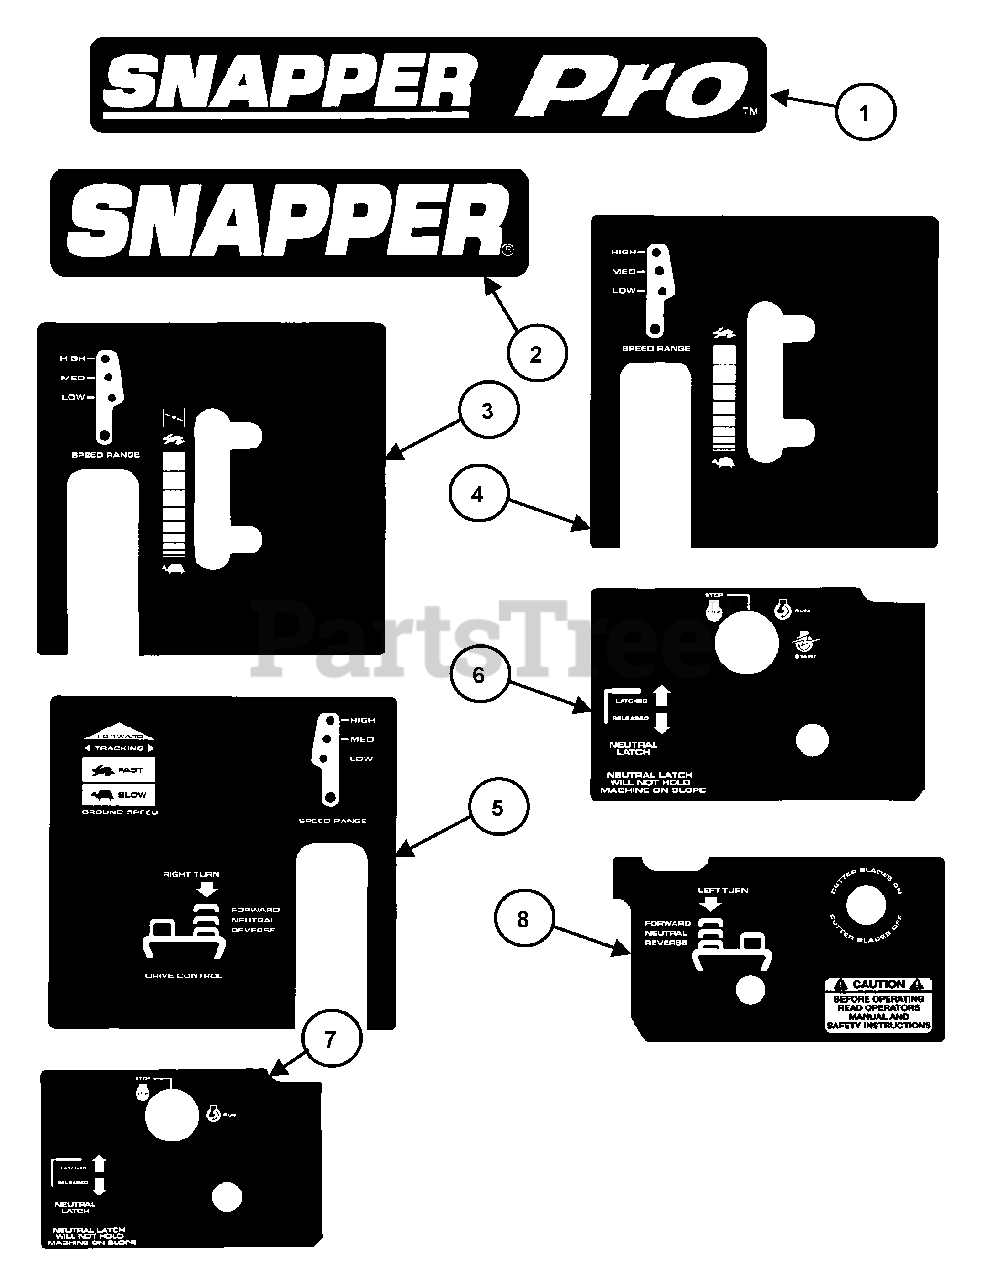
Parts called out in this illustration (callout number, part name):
1	DECAL, Snapper Pro
2	8" MOLDED LOGO, SNAPPER
3	DECAL, Left Panel, Throttle
4	DECAL, Left Panel, Throttle w/o Choke
5	DECAL, Right Panel, Instruction
6	DECAL, Right Panel, Switch, E. Start
7	DECAL, Right Panel, Switch
8	DECAL, Left Panel, Switch
